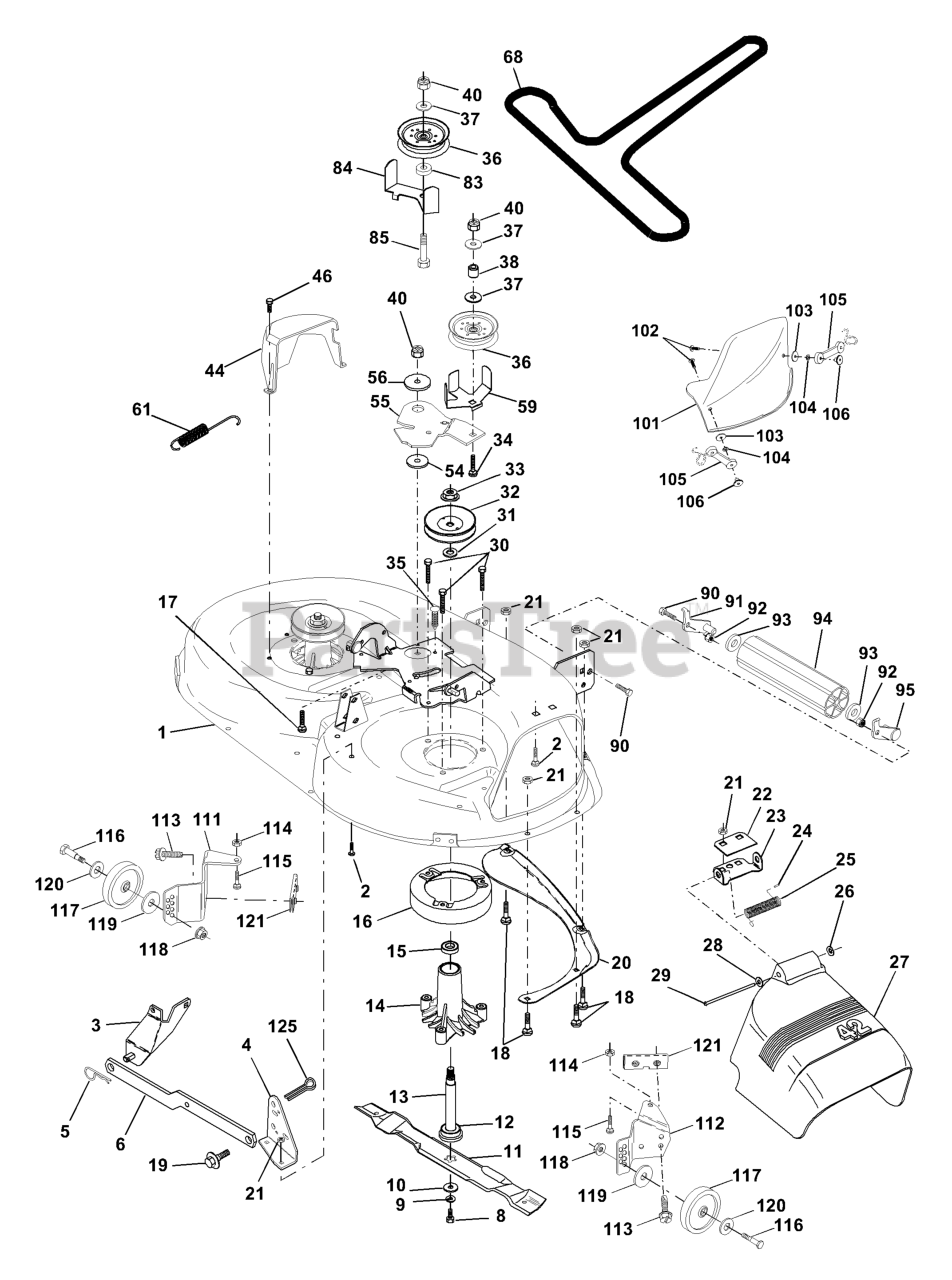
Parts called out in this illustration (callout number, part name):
1	DECK 42"
2	RP BOLT 5/16-18 X3/4 ZN/YEL GR
3	BRKT ASM SWAY BAR
4	BRKT DECK SW BAR
5	RETAINER-SPRNG RB
6	REAR SUSP ARM
8	BLADE BOLT
9	LOCKWASHER
10	WASHER.BLADE
11	BLADE.42".MULCH
12	BEARING.BALL.#6204.(MANDREL)
13	SHAFT ASM VENT
14	HOUSING.MANDREL.VENTED (MACHD)
16	STRIPPER
17	BOLT CARRIAGE
18	BOLT
19	BOLT SHD 5/16-18
20	BAFFLE
21	LOCKNUT
22	STIFFENER BRACKET
23	DEFLECTOR BRACKET
24	CAP-SLEEVE LT
25	SPRING TORSION
26	NUT PUSH M
27	SHIELD.DEFLECTOR.MOWER.42".BLK
28	Washer 11/32 X 5/8 X 16 Ga
29	ROD.HINGE
30	SCREW
31	WASHER
32	MANDREL PULLEY
33	NUT
35	FASTENER.XMAS.TREE
36	FLAT IDLER PULLEY
37	WASHER
38	IDLER SPRING SPACER
44	GUARD MANDREL LH BLACK
46	SCREW.1/4-20X5/8
54	HARDENED WASHER
55	IDLER ARM
56	SPACER RETAINER
59	GUARD, BELT
61	SPRING EXTENSION
68	V-BELT TRIPATH
84	KEEPER BELT
85	BOLT
90	BOLT
91	BRACKET LH (A)
92	NUT
93	Washer 17/32 X 7/8 X 16 Ga
94	NOSE ROLLER
95	BRACKET RH (B)
101	COVER MULCH 42"
102	SCREW
104	LOCKWASHER #10
105	LATCH ASSEMBLY
106	WELDNUT
111	BRACKET
112	BRACKET
113	SCREW.THDROL.5/16-18X3/4.TTY
114	NUT
115	BOLT.CARR.5/16-18X1/2
116	BOLT M
117	WHEEL.GAUGE.BLK.4.93
118	LOCKNUT
119	WASHER.5/16.FLAT.STE.STD.
120	Washer 17/32 x 15/16 x 12 Ga.
121	BRACKET.EXTRUDED.GAGE.WHEEL
125	Pin Cotter 1/4 x 1 Plated
